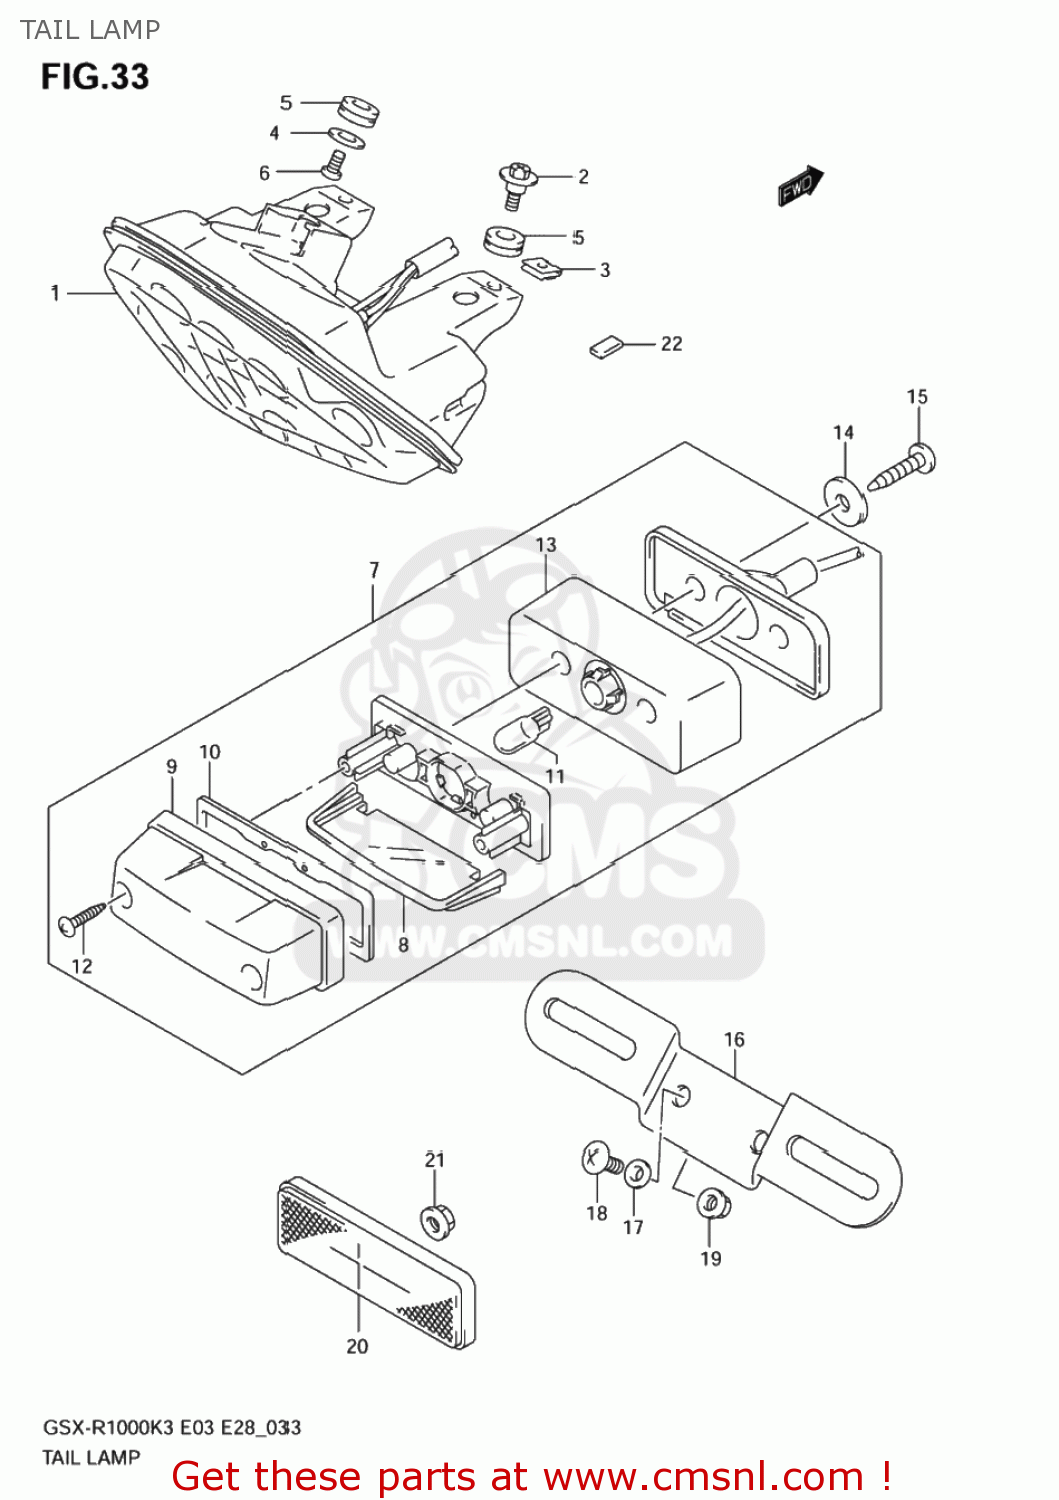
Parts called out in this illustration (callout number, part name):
1	LAMP ASSY,RR COMBINATION
2	SCREW(6X22.5)
3	NUT
4	WASHER(5.5X20X1.2)
5	CUSHION
6	SCREW
7	LAMP ASSY,LICENSE
8	LENS
9	COVER
10	GASKET (NAS)
11	BULB(12V5W)
12	SCREW
13	SPACER
14	WASHER(5.5X20X1.2)
15	SCREW, LICENSE LAMP
16	BRACKET,LICENSE PLATE
17	WASHER(6.5X20X1.6)
18	SCREW
19	NUT
20	REFLECTOR ASSEMBLY,REAR
21	NUT
22	CUSHION,RR COMBINATION
